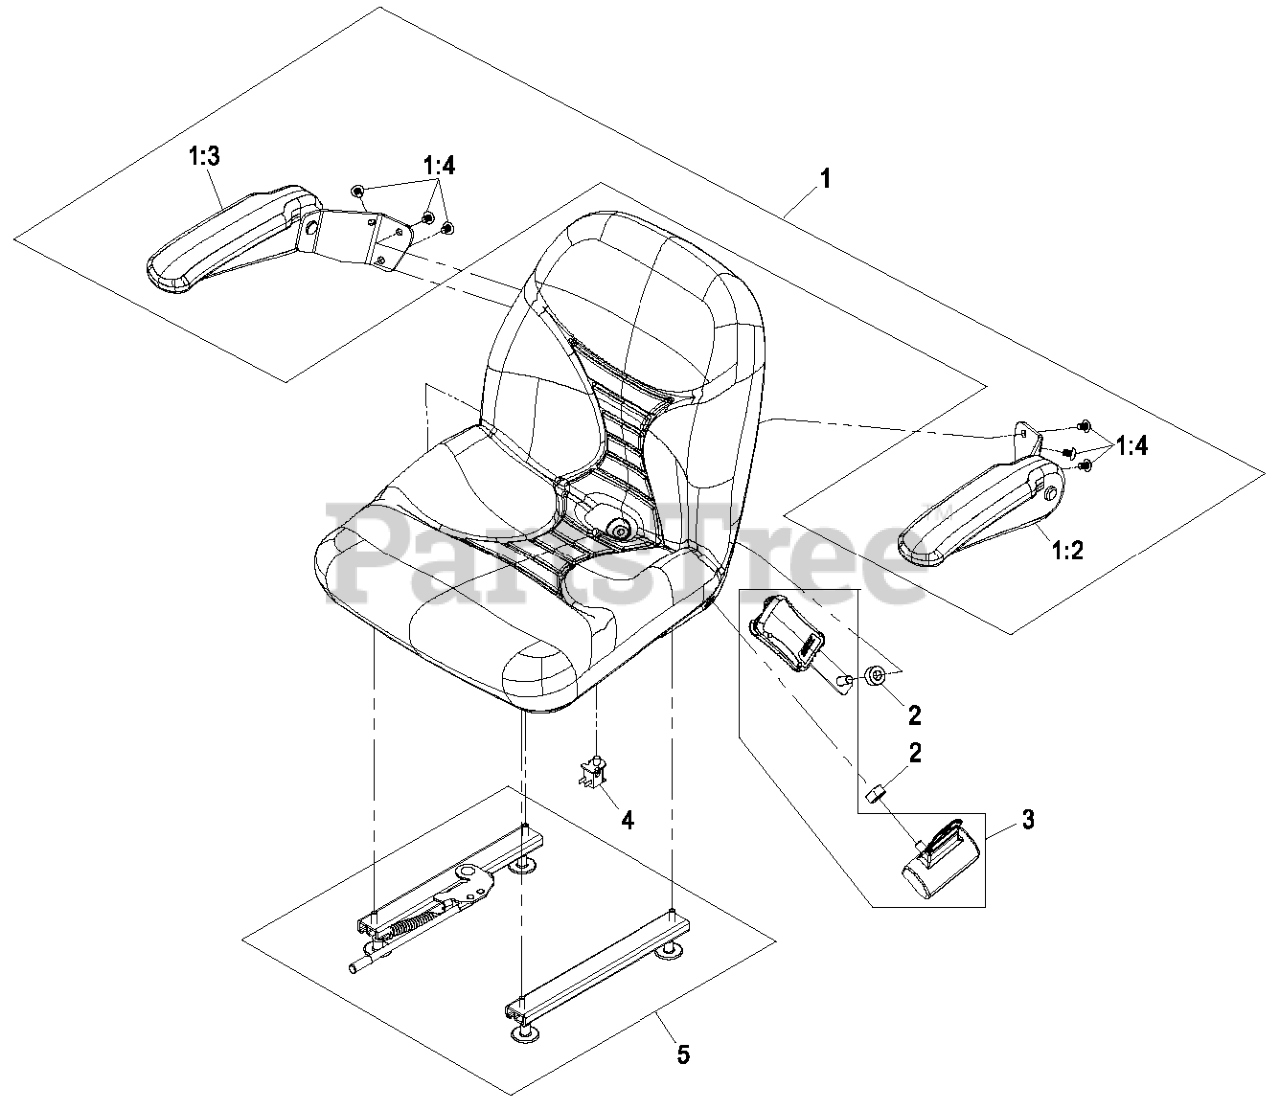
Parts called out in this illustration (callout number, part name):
1	ARMREST KIT
1:2	LH ARMREST KIT
1:3	RH ARMREST KIT
1:4	SCREW-HSBH
3	SEAT BELT KIT
4	SWITCH-BAIL
5	SEAT TRACK KIT
